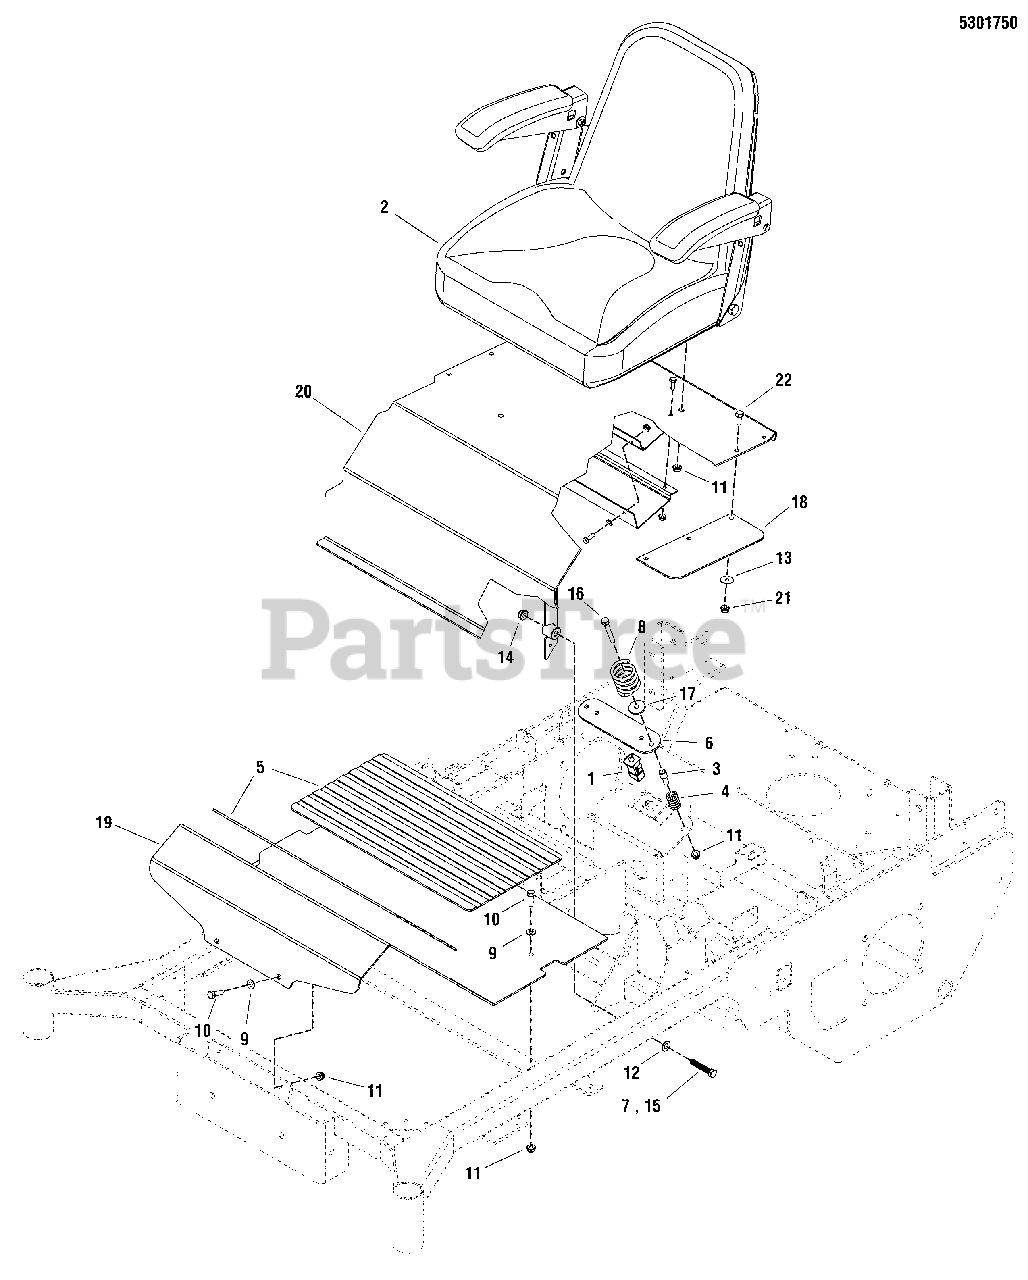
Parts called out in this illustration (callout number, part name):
1	SWITCH, Plunger, Snap-In, NO/NO
2	SEAT - 2012
2	SEAT, LOW, COMPANION
2	SEAT, GRAY, NO LOGO, CMPT
3	SPACER, .33 X .66 X 1.31 SHLDR, CZ
4	SPRING-COMP, .720ID X 1.310LG X .118 WIRE
5	SAFETY WALK, 10.00 X 19.00
6	PLATE, SEAT SWITCH - RED
7	BOLT, 3/8-16 X 3-1/2" GD5 CZ
8	SPRING, SEAT SUPPORT
9	WASHER, 5/16" SAE
10	BOLT, 5/16-18 X 1" GRD5 YZ
11	NUT, 5/16-18 HEX NYLOCK FLANGE NUT
12	WASHER, 3/8 SAE
13	WASHER, 1/4" Fender
14	NUT, 3/8 - 16 HEX NYLOCK FLANGE
15	BOLT, 3/8-16 X 2-1/2" GD5 CZ
16	BOLT, 5/16-18 X 2-1/4" GD5 YZ
17	WASHER, .34 X 1.25 X 10 GA
18	PLATE, SEAT, RUBBER FLAP
19	PLATE, FLOOR PAN, SNP 61 - RED
19	PLATE, FLOOR PAN, S200XT - RED
20	ASSM, SEAT PLATE W/ DECALS, S200XT - RED (5408309D)
20	WELD, SEAT PLATE - RED
20	WELD, SEAT PLATE, S200XT - RED
21	NUT, 1/4-20 Hex Nylock Flange
22	BOLT,1/4-20X0.750,GR5,STD NECK,SQ,ZC/CL
23	SEAT BACK COVER, SEAT 2012
23	SEAT BACK COVER
24	SEAT COVER
24	SEAT CUSHION
25	Arm Rest Asm. (set of 2)
26	SLIDE RAILS
